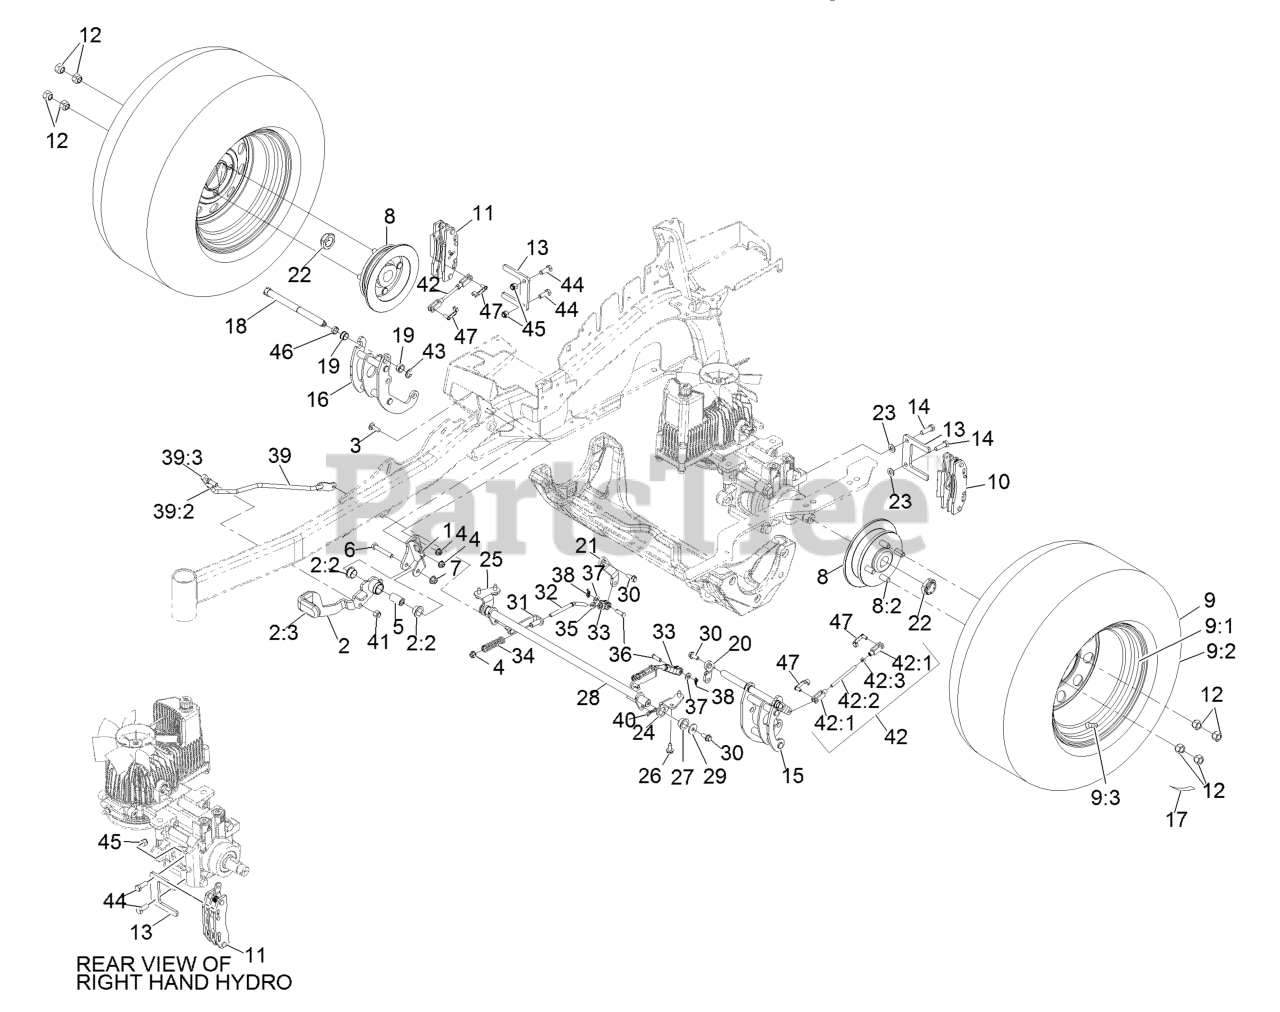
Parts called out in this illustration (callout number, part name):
1	BRACKET-MOUNT
2	BRAKE LEVER ASM W/ GRIP
2:2	BUSHING-FLANGE
2:3	GRIP-LEVER
3	BOLT-CARR
4	NUT-HF, NI
5	HANDLE-PIVOT, BRAKE
6	SCREW-HH
7	NUT-HF, NI
8	WHEEL HUB ASM
8:2	STUD-WHEEL
9	WHEEL AND TIRE ASM
9:3	Stem-Valve
10	CALIPER-BRAKE
11	CALIPER-BRAKE, RH
12	NUT-LUG
13	PLATE-MOUNT, BRAKE
14	SCREW-LOCK, PATCH
15	MOUNT-BELLCRANK, LH
16	MOUNT-BELLCRANK, RH
17	DECAL-TORQUE, WHEEL HUB LUG
18	BELLCRANK
19	BUSHING
20	ARM-INNER, LH
21	ARM-INNER, RH
22	LOCKNUT
23	WASHER-FLAT
24	MOUNT-PIVOT, LH
25	MOUNT-PIVOT, RH
26	Screw-HWH 5/16-18 X 3/4 Tf
27	BUSHING-FLANGE
28	SHAFT-CROSS
29	WASHER-FLAT
30	SCREW-HHF
31	BRACKET-L
32	LINKAGE-MID
33	YOKE-OFFSET
34	SPRING-COMPRESSION
35	NUT-JAM
36	PIN-CLEVIS
37	WASHER-PLAIN
38	PIN-COTTER, LOCKING
39	FRONT LINKAGE ASM
39:2	END-TIE ROD, RH
39:3	NUT-HJ
40	PIN-COTTER, LOCKING
41	NUT-LOCK
42	REAR LINKAGE ASM
42:3	NUT-JAM
44	SCREW-HH
45	NUT-LOCK, NI
47	PIN-CLEVIS, SPRING
